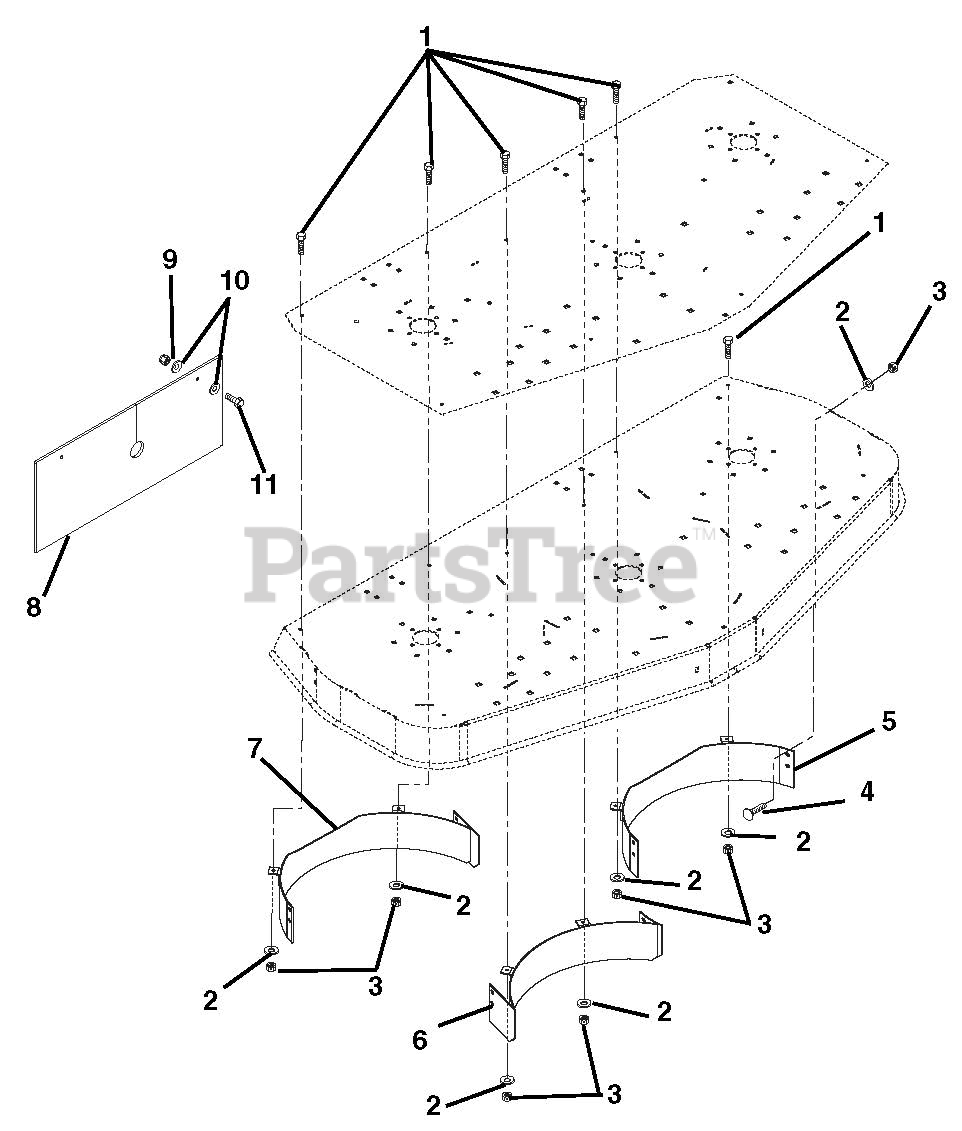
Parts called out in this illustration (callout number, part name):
1	BLT-HEX .31-18X1.00 GR5 YWZC
2	WSHR-FL-STL.312X.734X.065 YWZ
3	NUT-LK-NYL .312-18 YWZC
4	BLT-RDHDSQNK .31-18X.75 G5YZ
5	BAFFLE, WELDMENT LEFT
6	BAFFLE, WELDMENT CENTER
7	BAFFLE, WELDMENT RIGHT
8	SHIELD,GRASS
9	NUT-LK-NYL .38-16 YWZC
10	WSHR-FL-STL.406X.812X.065 YWZ
11	BLT-HEX .38-16X1.00 GR5 YWZC
